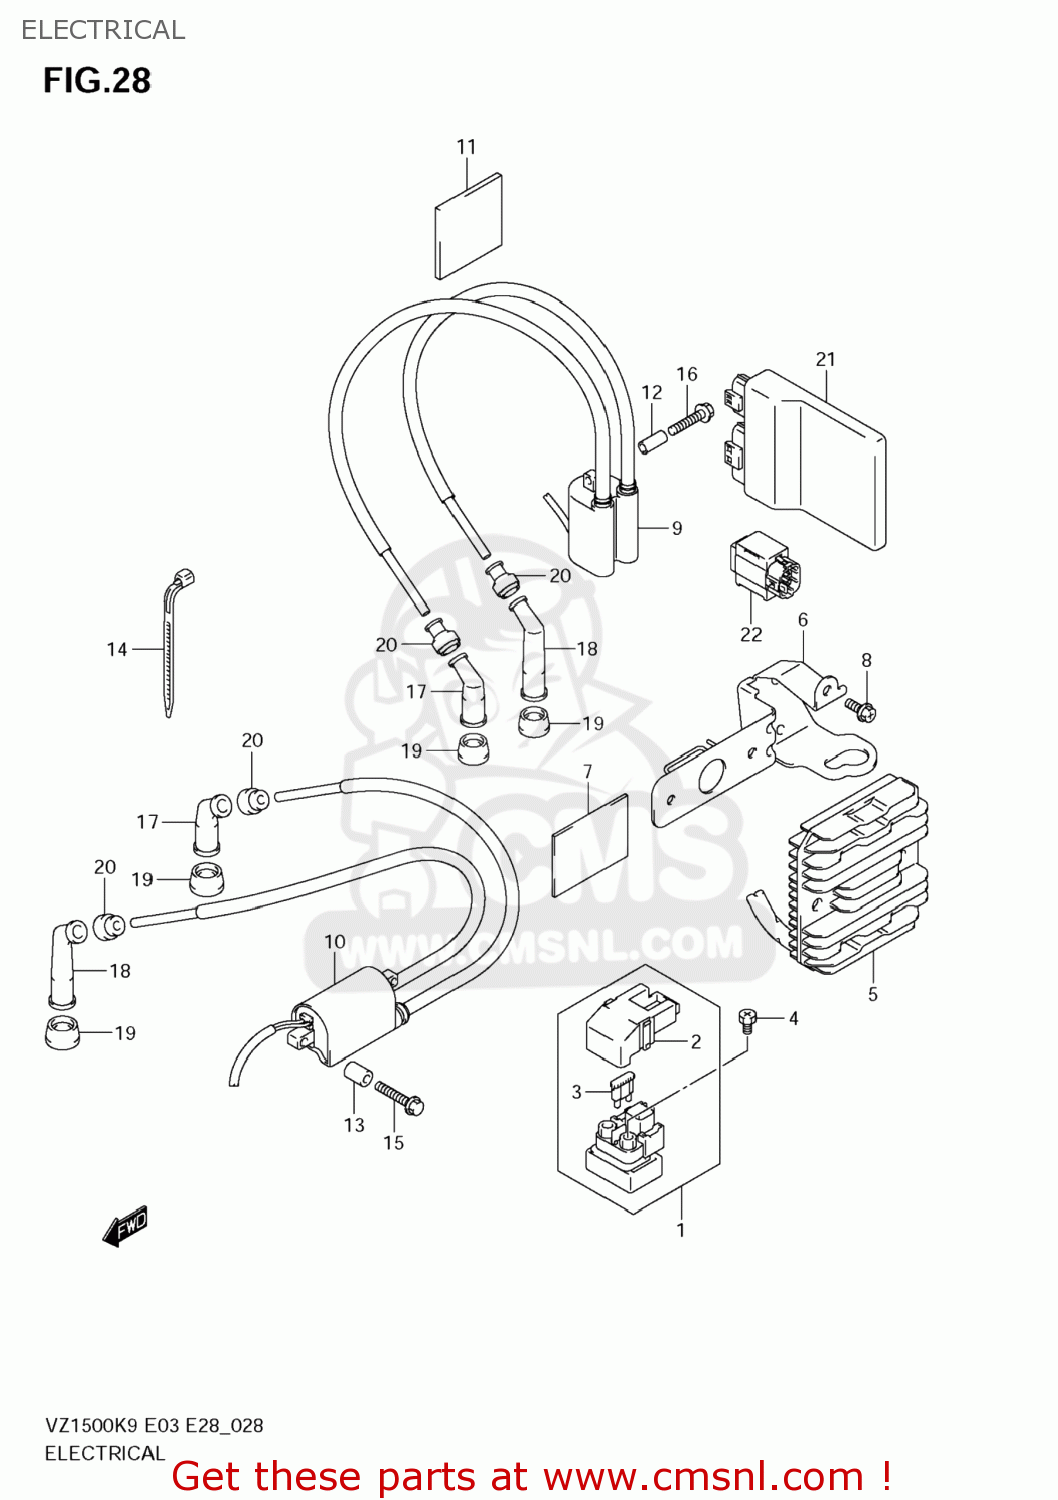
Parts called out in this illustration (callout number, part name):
1	RELAY ASSY,STARTING MOTOR
2	COVER
3	FUSE(30A)
4	SCREW(6X8)
5	RECTIFIER ASSY
6	BRACKET,RECT FTG
7	PROTECTOR(80X80X2)
8	SCREW
9	COIL ASSY,IGNITION RR
10	COIL ASSY,IGNITION FR
11	CUSHION,HIGH TENSION CORD
12	SPACER(6.4X10X22)
13	SPACER(6.2X12X16)
14	CLAMP(L:165)
15	BOLT
16	BOLT
17	CAP,SPARK PLUG
18	CAP ASSY,SPARK PLUG
19	SEAL,SPARK PLUG
20	SEAL,HIGH TENSION CORD
21	CONTROL UNIT,FI
22	SENSOR ASSY,FUEL CUT
